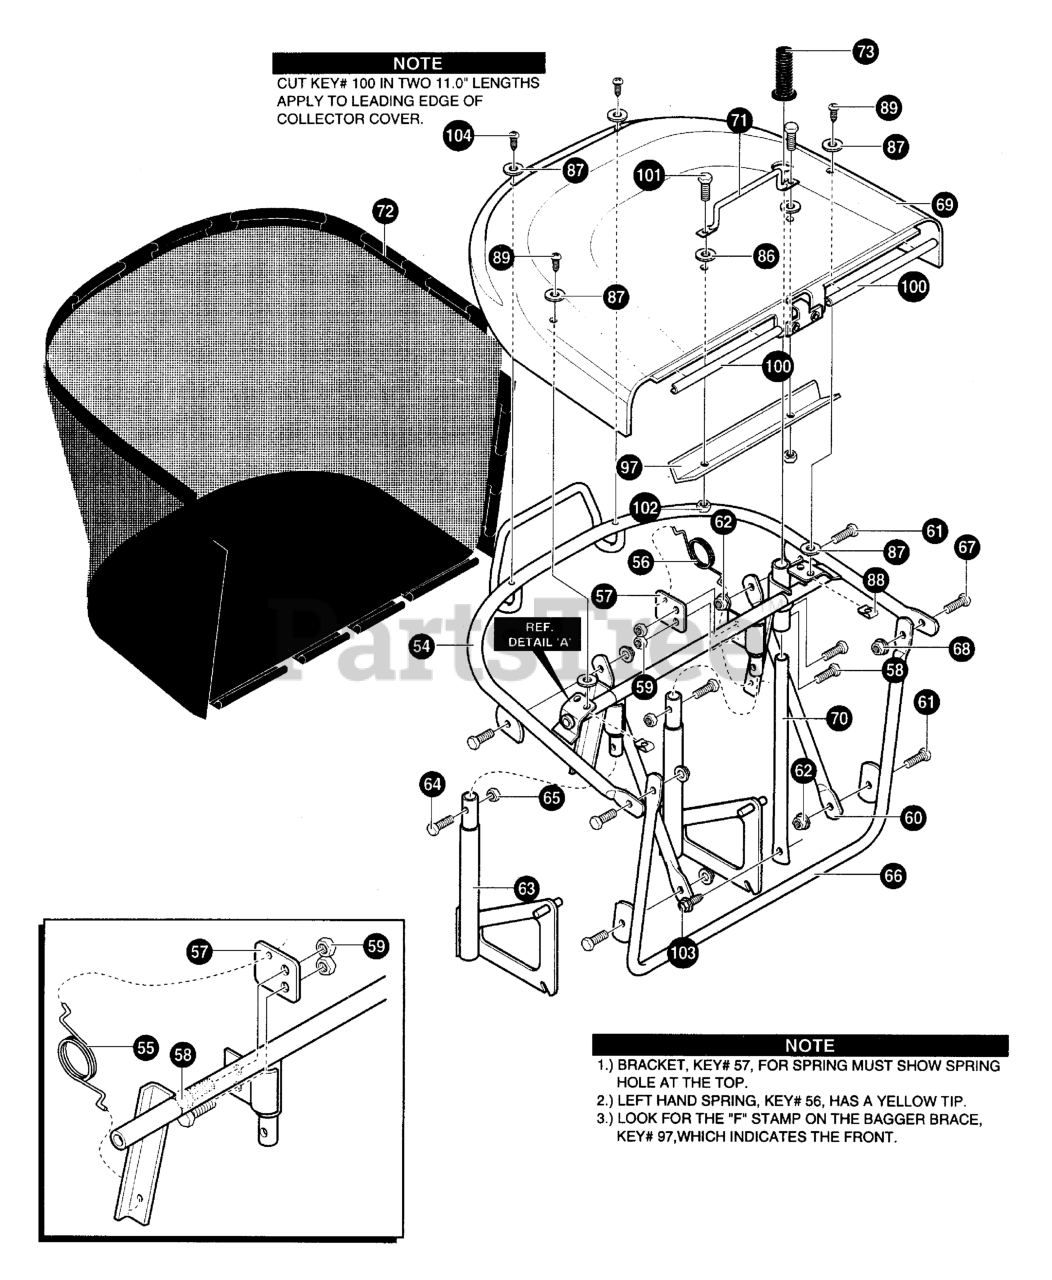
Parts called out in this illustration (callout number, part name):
54	ASM. WELD UPPER FRAME
55	SPRING, TORSION RH
56	SPRING, TORSION LH
57	BRACKET, SPRING COLLECTOR
58	SCREW, 1/4-20X.50 HHC
59	NUT, 1/4-20 REGHEXCTRLK
60	BRACE, FRAME COLLECTOR
61	SCREW, 1/4-20X.62 HHC
62	NUT, 1/4-20HEXNYL
63	WELD ASM., SUPPORT COLLECTOR
64	SCREW, 1/4-20X1.50
65	NUT, 1/4-20 REGHEXCTRLK
66	WELD ASM., FRONT FRAME COLLECT.
67	SCREW, 1/4-20X.62 HHC
68	NUT, 1/4-20 HEXNYL
69	TOP COLLECTOR ASM.
70	HANDLE, DUMP COLLECTOR
71	HANDLE, REBA COLLECTOR
72	REBA COLLECTOR BAG
73	RUBBER GRIP
86	WASHER, .281X1.25X.06
87	WASHER, .328X1.06X.062
88	NUT, 1/4-20 TINN U
89	SCREW, 1/4-20X.63 PHPNHD
97	BRACE, BAGGER
100	TRIM 77.5 INCHES
101	SCREW 1/4-20X1.50 PHPNHD
102	NUT, 1/4-20 HEXNYL
103	SCREW, 10-24X.38 SLHWATAP
104	SCREW, #12X.50 PHPNHTAP
